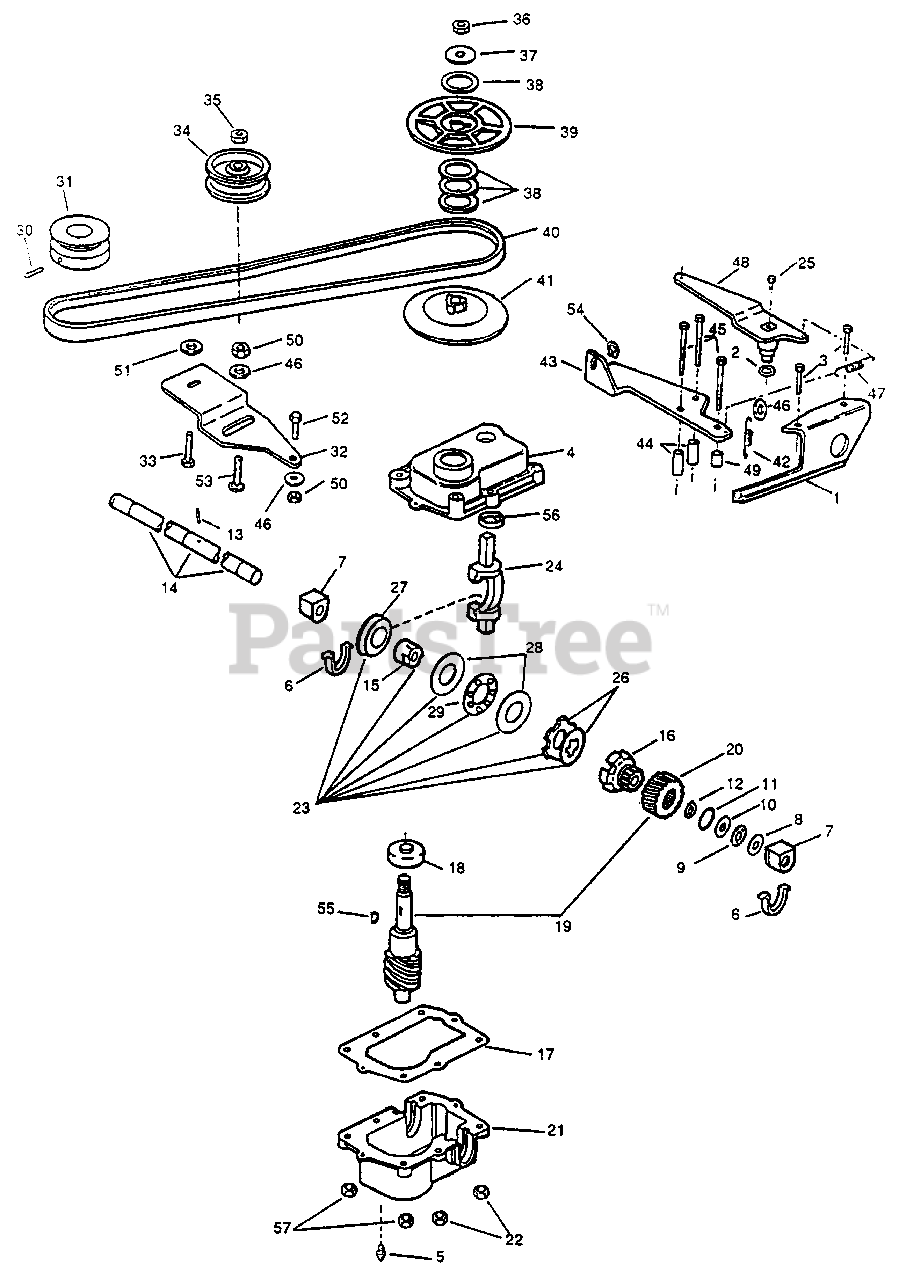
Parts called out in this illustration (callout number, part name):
1	Tensioner Bracket
2	O-Ring
3	Hex Hd. Cap Screw
4	Gearcase-Upper
5	Plug
6	Packing
7	Bearing & Seal-Gearcase
8	Thrust Washer
9	Thrust Bearing
10	Thrust Washer
11	Thrust Washer
12	Retaining Ring
13	Pin
14	Driveshaft
15	Driven Sleeve
16	Driver
17	Gasket
18	Bearing
19	Worm Wheel & Shaft (Inc. 20)
20	Worm Wheel
21	Gearcase-Lower
22	Nut, Lock
23	Collar, Brg & Disc Kit (Inc. 24-29)
24	Shift Fork
25	Screw
26	Disc Plate Kit
27	Collar
28	Thrust Washer
29	Bearing
30	Set Screw
31	Pulley-Engine
32	Bracket & Idler Assy (Inc. 33-35)
33	Screw
34	Pulley-Idler
35	Nut
36	Nut
37	Washer
38	Washer
39	Pulley-Upper Half
40	V-Belt
41	Pulley-Lower Half
42	Extension Spring
43	Conduit Anchor Bracket
44	Spacer
45	Screw
46	Washer
47	Extension Spring
48	Shift Arm & Hub Assembly
49	Spacer
50	Nut
51	Washer
52	Screw
53	Square Neck Bolt
54	Retaining Ring
55	Key
56	Seal Guide
57	Nut-Lock
